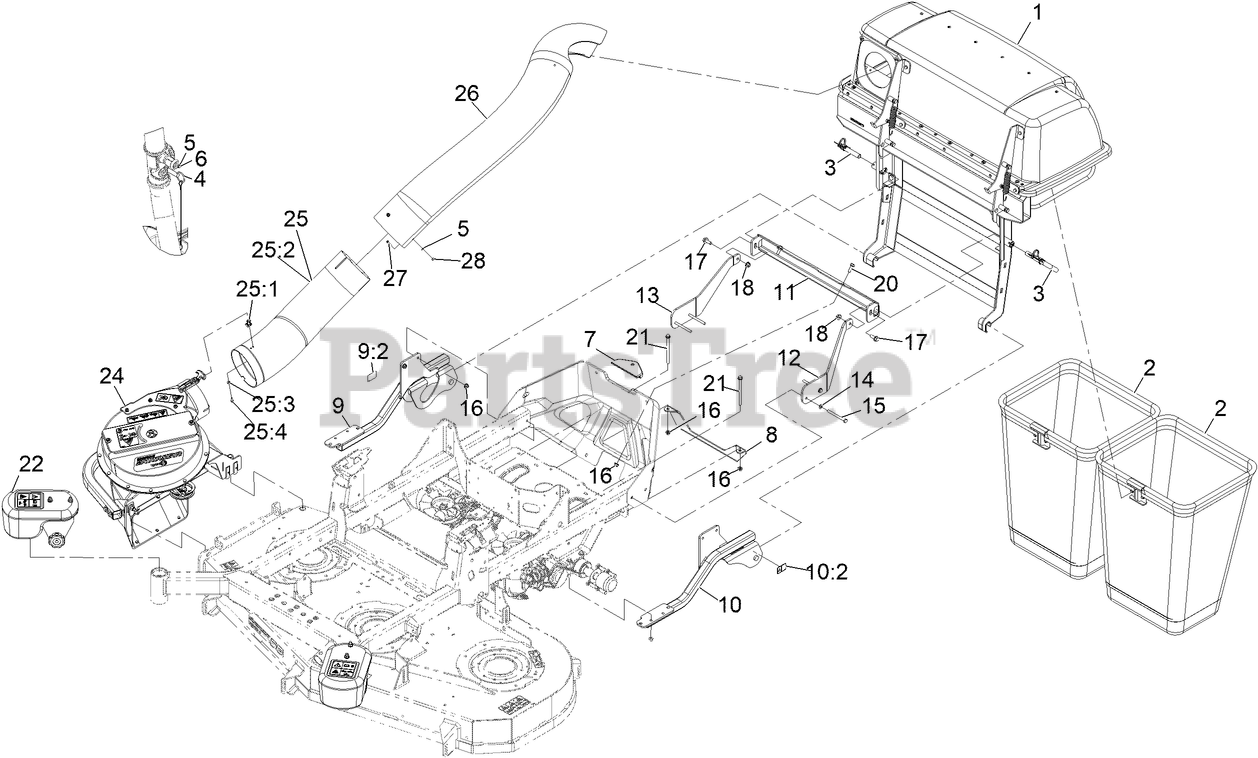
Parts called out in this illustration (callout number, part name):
1	Asm, Hood & Frame
2	BAG AND FRAME ASM
3	PIN-MOUNT, BAGGER
4	HITCH PIN ASM
5	WASHER-FLAT
7	COVER-HITCH
8	SUPPORT-TRANSMISSION
9	ASM, BAGGER MOUNT W/ DECAL, RT
9:2	DECAL-WARNING
10	ASM, BAGGER MOUNT W/ DECAL, LT
10:2	DECAL-WARNING
11	MOUNT-BAGGER LWR
12	BRACKET-UPPER, LH
13	BRACKET-UPPER, RH
14	WASHER-PLAIN
16	NUT-HF, NI
17	SCREW-HHF 3/8-16 X 1
18	NUT-HF, NI
20	SCREW-HHF
21	SCREW HHF
22	CASTER WEIGHT KIT
24	ASM, UV BLOWER
25	LOWER TUBE ASM
25:1	Tube, Lower Short
25:2	LATCH-KEEPER
25:3	SCREW-PPH
25:4	WASHER-FLAT
26	TUBE-UPPER
27	SCREW-HWH
28	NUT-LOCK, NI
